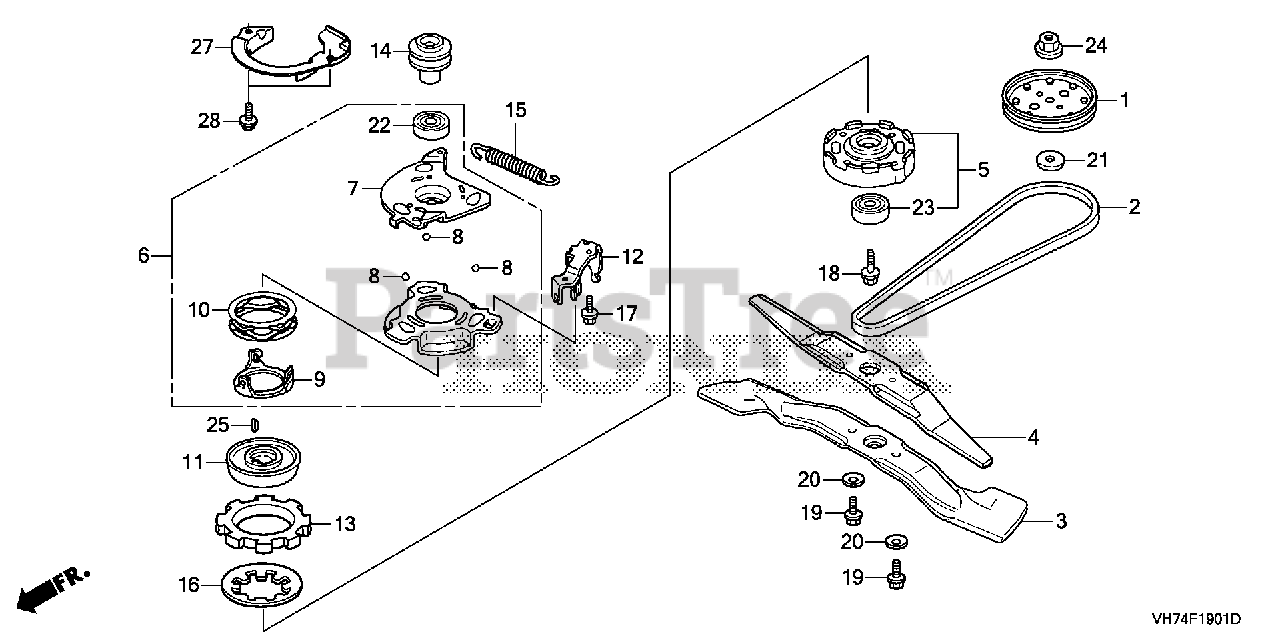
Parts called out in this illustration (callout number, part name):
2	V-BELT (3L-38.6)
3	BLADE, ROTARY
4	BLADE, ROTARY (UPPER)
5	HOLDER ASSY., BLADE
6	PLATE ASSY., BALL CONTROL
7	PLATE, BALL CONTROL
8	BALL, STEEL
9	PLATE, SPRING HOOK
10	SPRING, BALL PLATE
11	DISK, DRIVE
12	HOOK, RETURN SPRING
13	DISK, DRIVEN
14	PULLEY, DRIVE
15	SPRING ASSY., CLUTCH RETURN
16	SPRING, CLUTCH
17	BOLT, FLANGE (6X14)
18	BOLT, FLANGE (10X24)
19	BOLT, HEX. (10X20)
20	WASHER, SPRING (10MM)
22	BEARING, RADIAL BALL (6006) (SST)
22	BEARING, RADIAL BALL (6006) (TSB)
23	BEARING, RADIAL BALL (6204)
25	KEY, WOODRUFF (16X15)
27	GUIDE, ENGINE BELT
28	BOLT, FLANGE (6X14)
